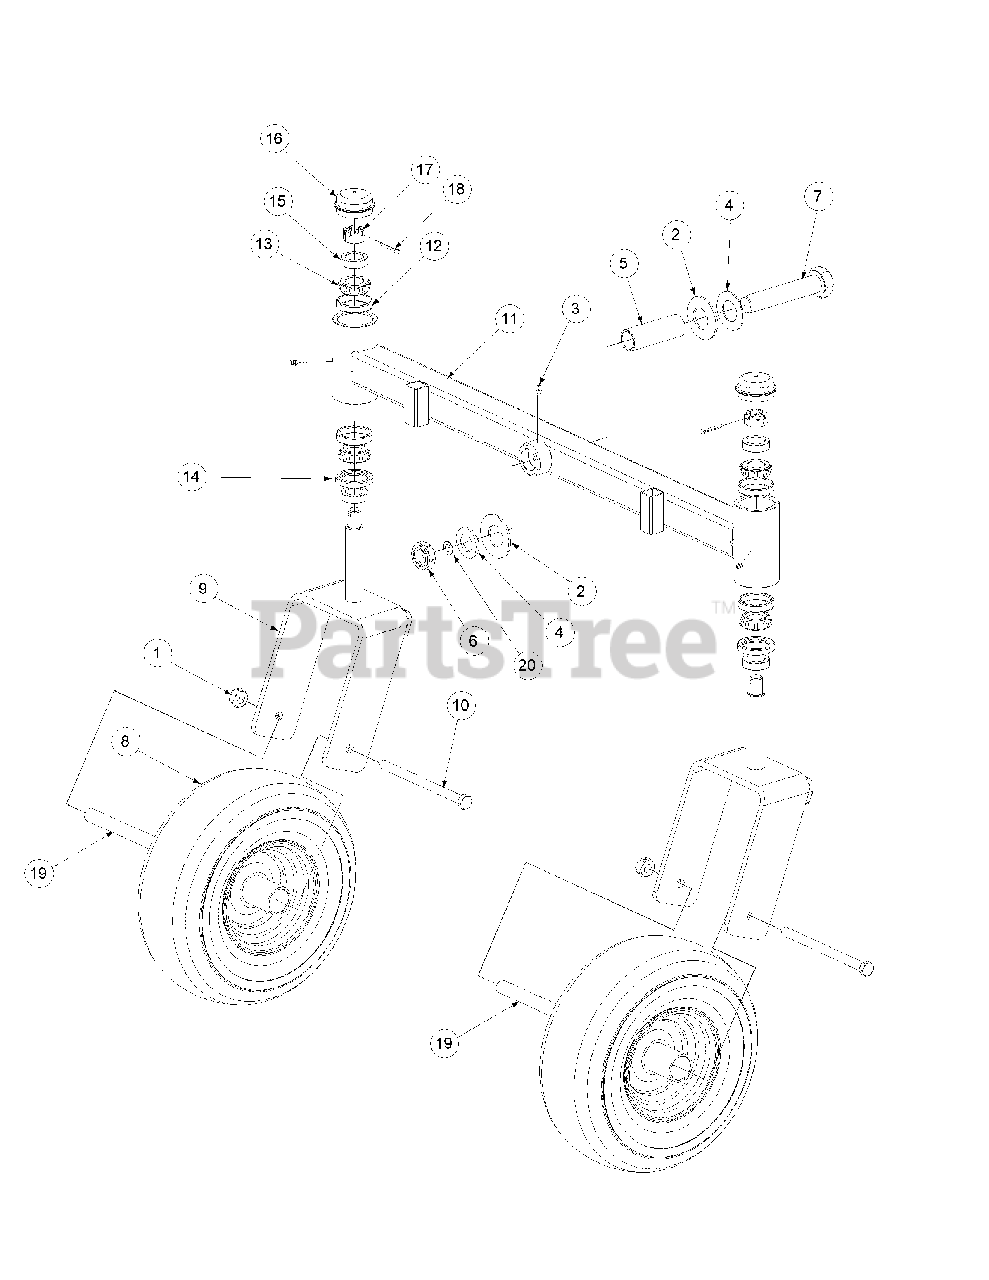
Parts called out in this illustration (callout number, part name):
1	Nut, 1/2-20, Center Lock
2	Bell Washer, 1.25 ID
3	Grease Fitting
4	Flat Washer, 1.00 ID
5	Spacer, 1.005 ID x 1.25 OD x 3.6
6	Nut, Jam, 1.0-14, Insert Lock
7	Hex Cap Screw, 1-14 x 5.0
8	Wheel, 13 x 5-6, White: Includes;
10	HHCS, 1/2-20, 7.25
11	Straight Front Axle
12	Cup Bearing
13	Bearing Cone
14	Seal
15	Ring Seal
16	Grease Cap, 1.986 OD
17	Slotted Nut, 3/4-16
18	Cotter Pin, 5/32, 1.25
19	Wheel Spacer
20	Retainer Extension, Self Locking
